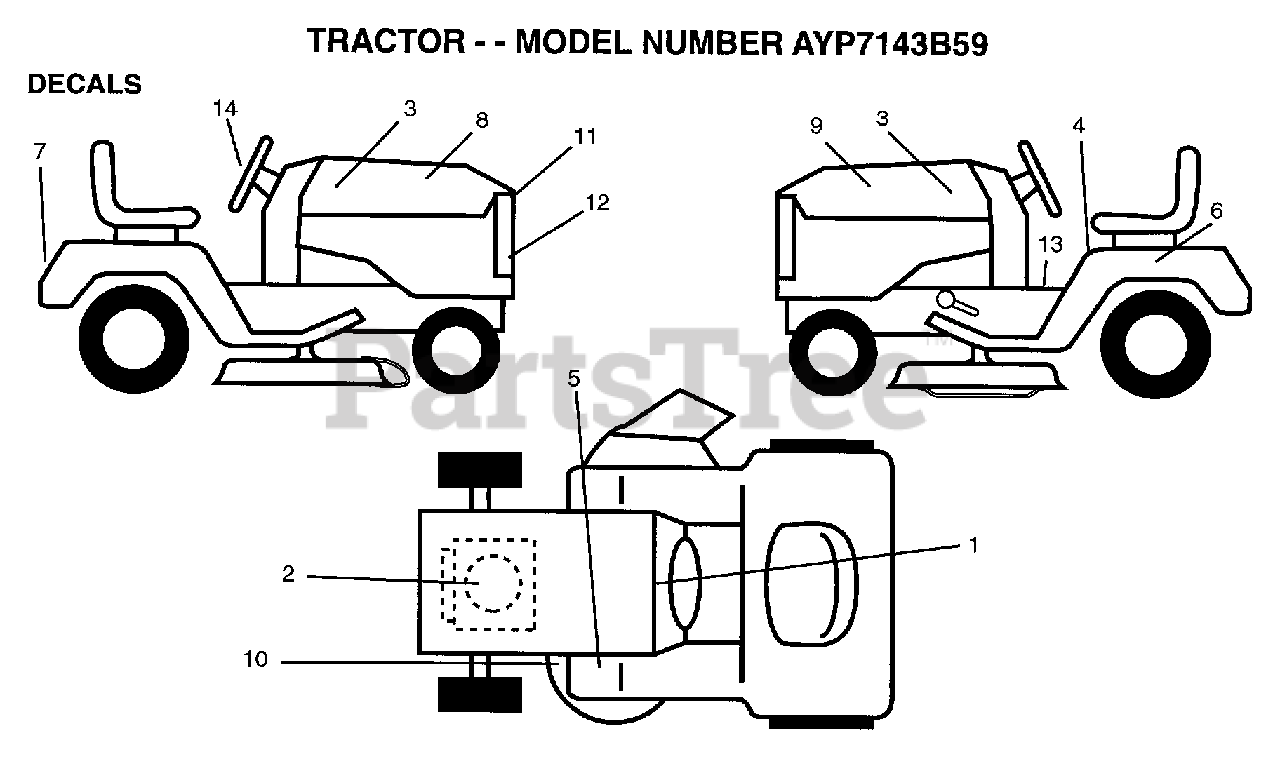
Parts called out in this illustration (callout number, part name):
1	DECAL.DASH.INST.
2	DECAL, ENGINE
3	DECAL.INS.HD.14.5
4	DECAL
6	DECAL.BATRY.3-3908
8	DECAL HOOD RH WIZ
9	DECAL HOOD LH WIZ
10	DECAL
11	DECAL GRILL WIZ
12	DECAL GRILL WIZ
13	DECAL BRAK PARK
